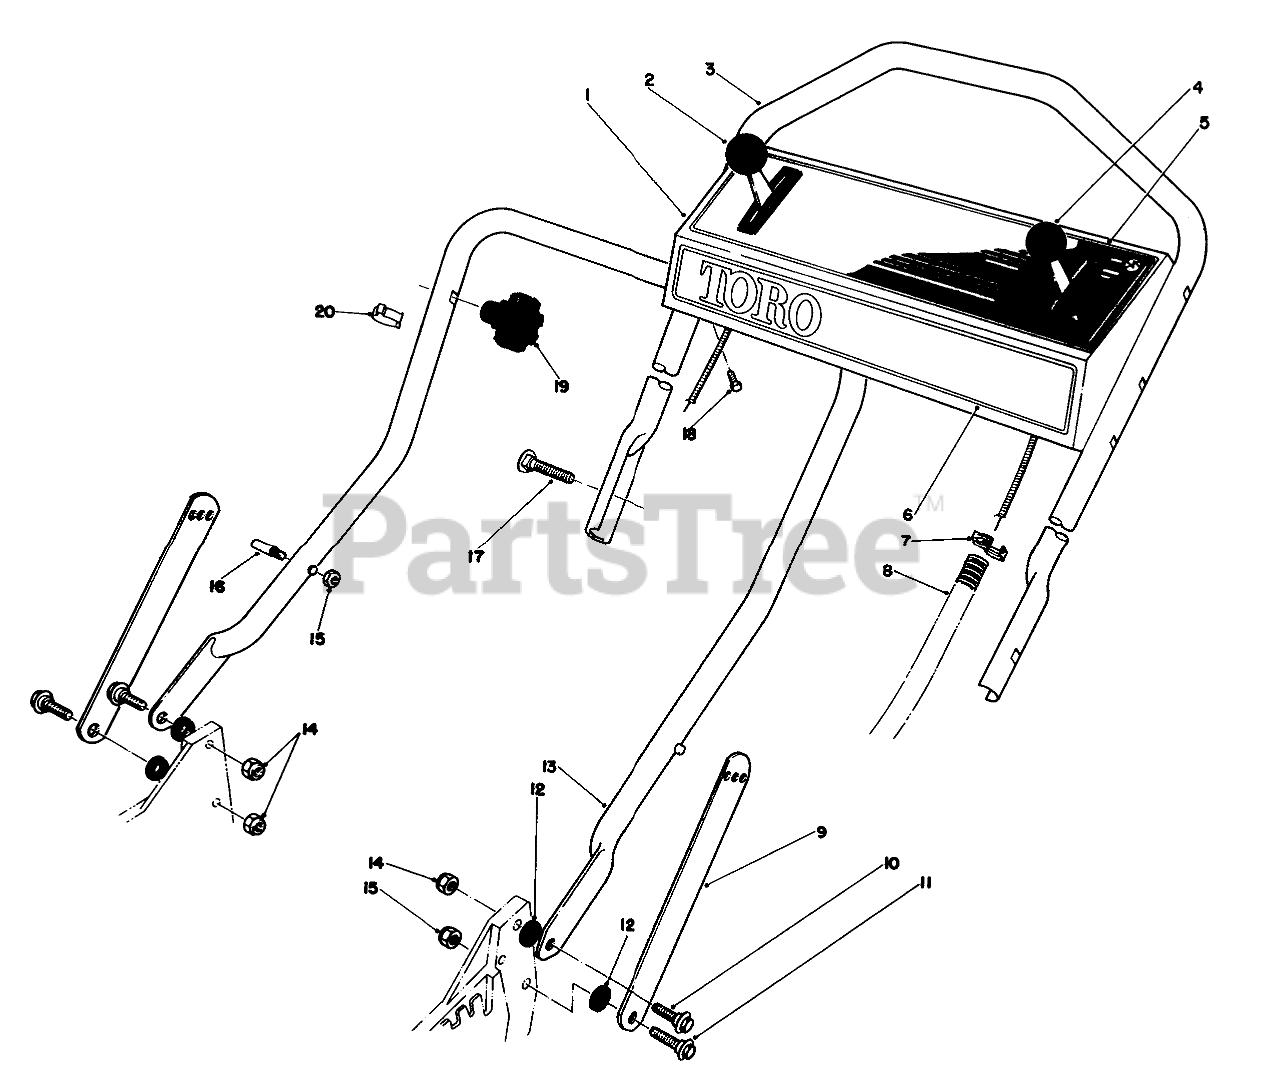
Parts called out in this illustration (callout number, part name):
1	Panel-Control (Incl. Ref. #5)
2	GROUND SPEED CONTROL
3	Handle-Upper
4	Throttle Control (Bend Type 2)(Sheath Lg. 54-1/4 inch. 137.8 cm)(Wire Lg. 2-1 inch. 6.4 cm)
5	Decal-Instruction Panel
6	Decal-Toro
7	FITTING-RING
8	CONTROL CABLE COVER
9	Handle Latch
10	SCREW-SHOULDER
11	SCREW-SHOULDER
12	SPACER
13	LOWER HANDLE ASM
14	NUT-LOCK, NI
15	Locknut
16	HANDLE PIN
17	5/16-18 X 2 HNDLE SCREW
18	SCREW-HWHTF
20	BOWDEN CLIP
